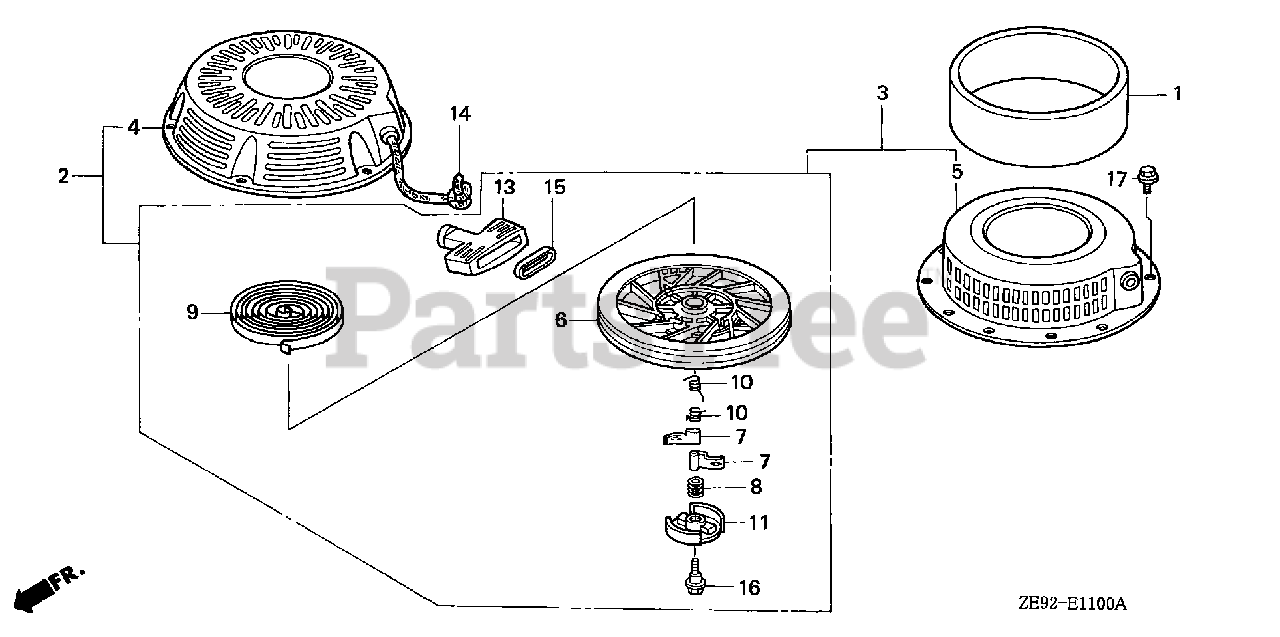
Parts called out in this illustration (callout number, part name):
2	STARTER ASSY., RECOIL *NH1* (BLACK)
2	STARTER ASSY., RECOIL *R280* (POWER RED)
4	CASE, RECOIL STARTER *NH1* (BLACK)
4	CASE, RECOIL STARTER *R280* (POWER RED)
6	PULLEY, RECOIL STARTER
7	RATCHET, STARTER
8	SPRING, FRICTION
9	SPRING, STARTER RETURN
10	SPRING, RATCHET
11	RETAINER, SPRING
13	GRIP, STARTER
14	ROPE, RECOIL STARTER
15	GRIP, REINFORCEMENT
16	SCREW, CENTER
17	BOLT, FLANGE (6X10)
